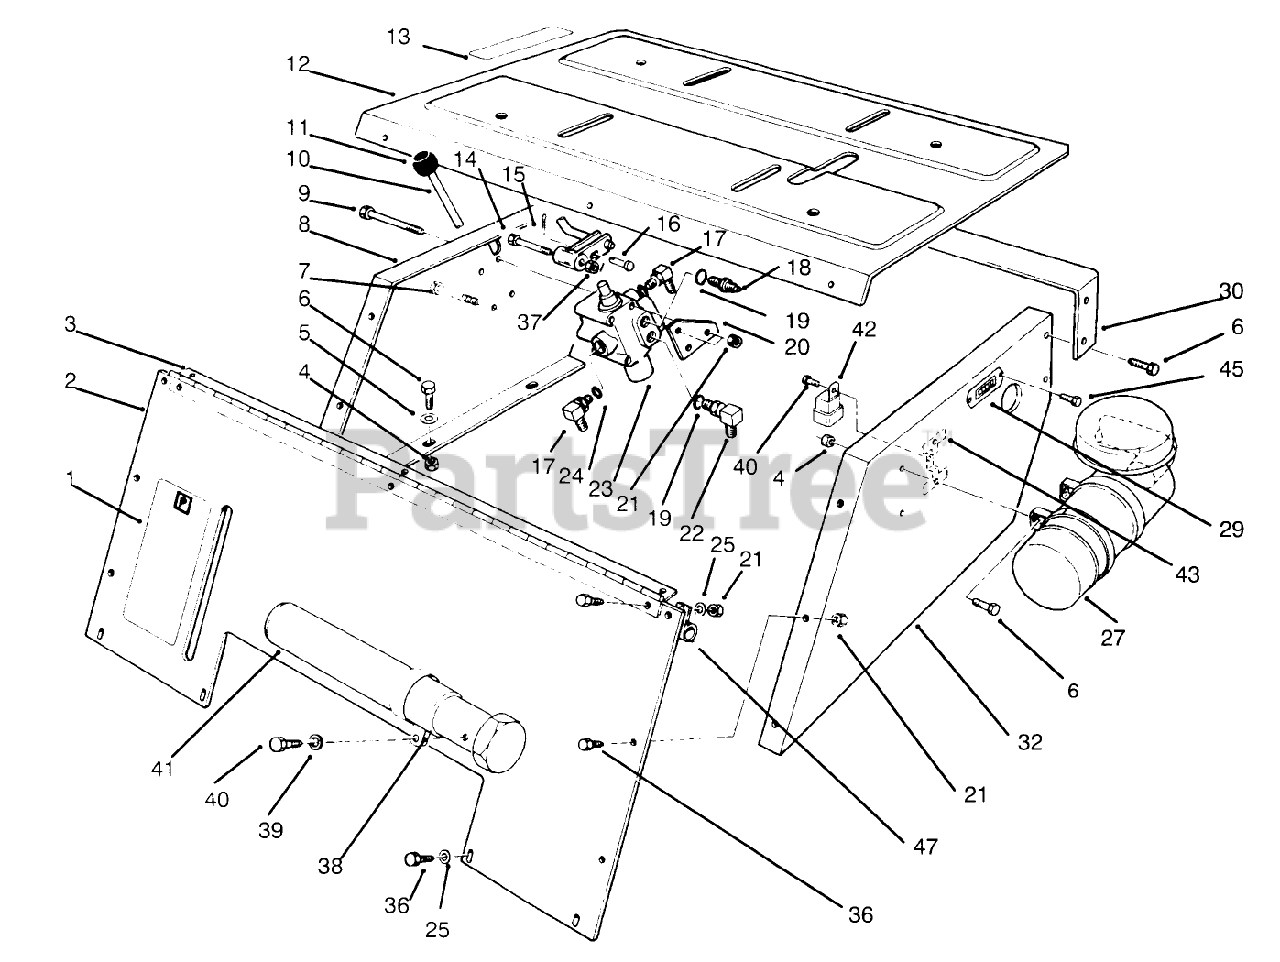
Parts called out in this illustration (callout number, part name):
1	PARK BRAKE DECAL
2	Support-Seat, Front
3	Hinge-Seat
4	NUT-LOCK, NI
5	WASHER-PLAIN
6	SCREW-HH
7	SCREW-HH
8	Support-Seat RH.
9	SCREW-HH
10	Lever-Valve
12	Plate-Seat
13	LIFT CONTROL DECAL
14	BOLT-WHEEL
15	PIN-COTTER
16	PIN-CLEVIS
17	FITTING-HYD, 90 DEG
18	FITTING-STRAIGHT
19	O-RING
20	LEVER BRACKET
21	NUT-LOCK, NI
22	FITTING-ELBOW, 90
23	VALVE ASM
24	O-RING
25	WASHER-FLAT
27	AIR CLEANER KIT
29	HOURMETER
30	Support-Hood
32	Support-Seat L.H.
36	SCREW-HH
37	NUT-LOCK, NI
38	CLAMP-R
39	WASHER-FLAT
40	SCREW-HWHTF
41	TUBE-MANUAL
42	RELAY
43	Bracket
45	SCREW-HWH
47	CLAMP-R
